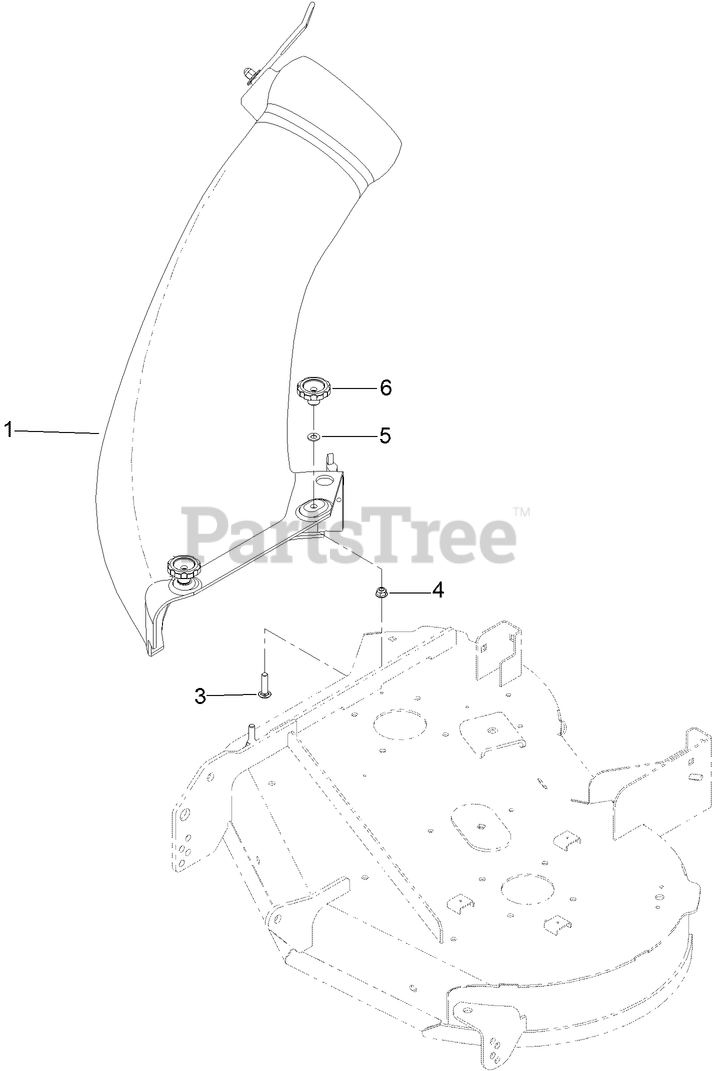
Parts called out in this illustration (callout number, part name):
1	34 INCH CHUTE ASM
3	SCREW-CARR
4	NUT-HF, NI
5	WASHER-PLAIN
